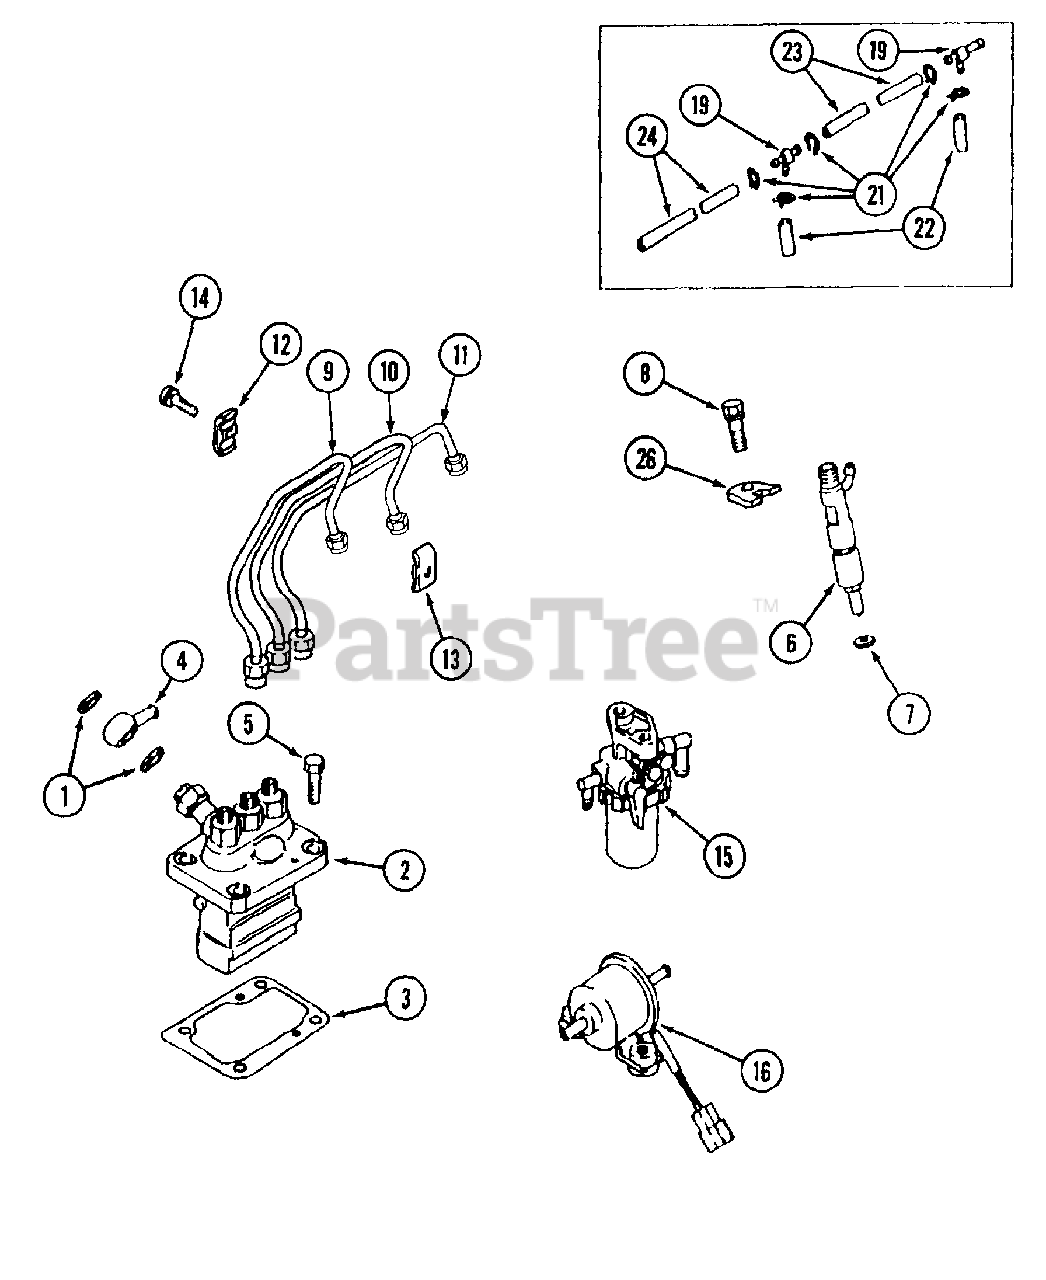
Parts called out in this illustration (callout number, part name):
1	Washer, Seal
2	Pump Ass'y., Fuel Injection
3	Shim Set, Adjusting
4	Collar, Union
5	Bolt
6	Nozzle & Holder Ass'y.
7	Gasket, Nozzle
9	Pipe Ass'y., Fuel Injection No. 1
10	Pipe Ass'y., Fuel Injection No. 2
11	Pipe Ass'y., Fuel Injection No. 3
14	Bolt, w/Washer
15	Filter Ass'y., Fuel
16	Pump Ass'y. Fuel
19	Pipe Ass'y.. Fuel Return
21	Clamp, Hose
22	Pipe, Rubber
23	Pipe, Rubber
24	Pipe, Rubber
26	Support, Nozzle
